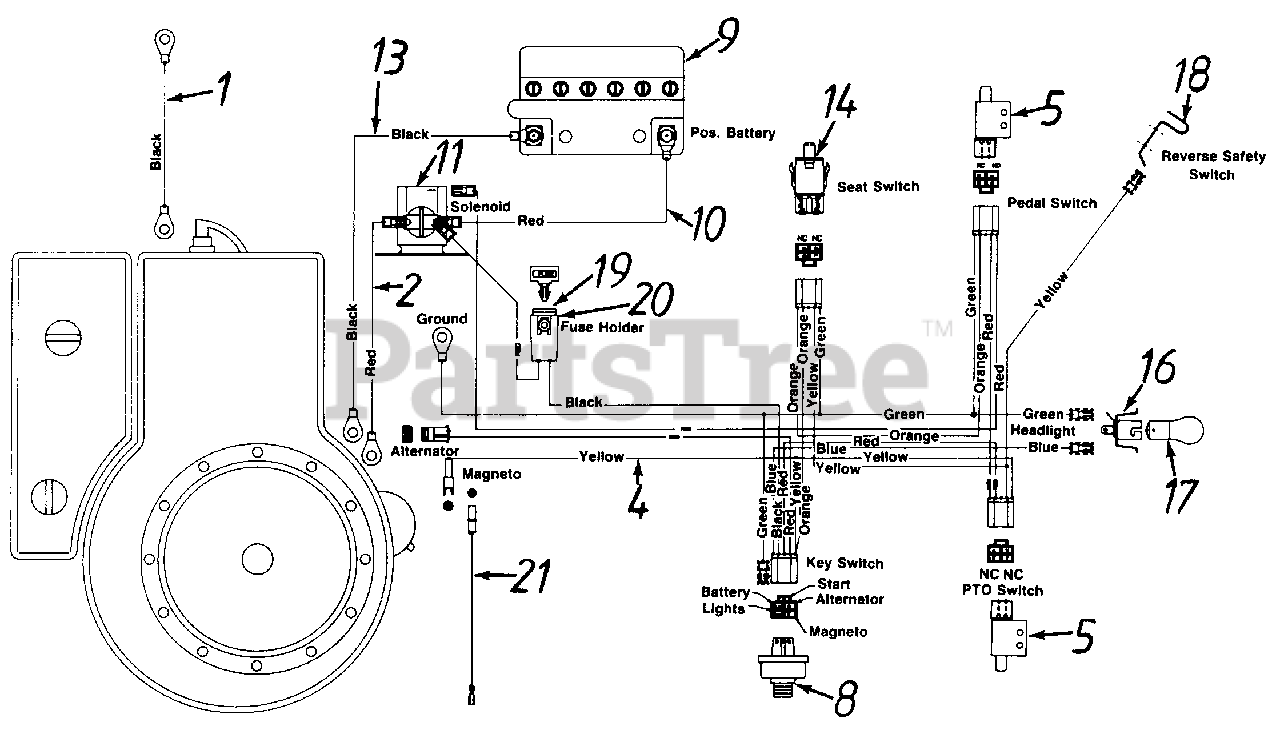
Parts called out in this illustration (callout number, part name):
1	Elec. Wire 8 Ga. x 9.0" Lg.
2	Elec. Wire
4	Wire Harness
5	Safety Switch
8	Ignition Switch
9	Battery 12V
10	Elec. Wire Red w/Boot
11	Solenoid
13	Elec. Wire 8 Ga. x 17" Lg.
14	Seat Switch
16	Headlight Socket
17	Lamp
18	Safety Switch
19	Fuse, Automotive Type 7-1/2 Amp.
20	Fuse Holder
